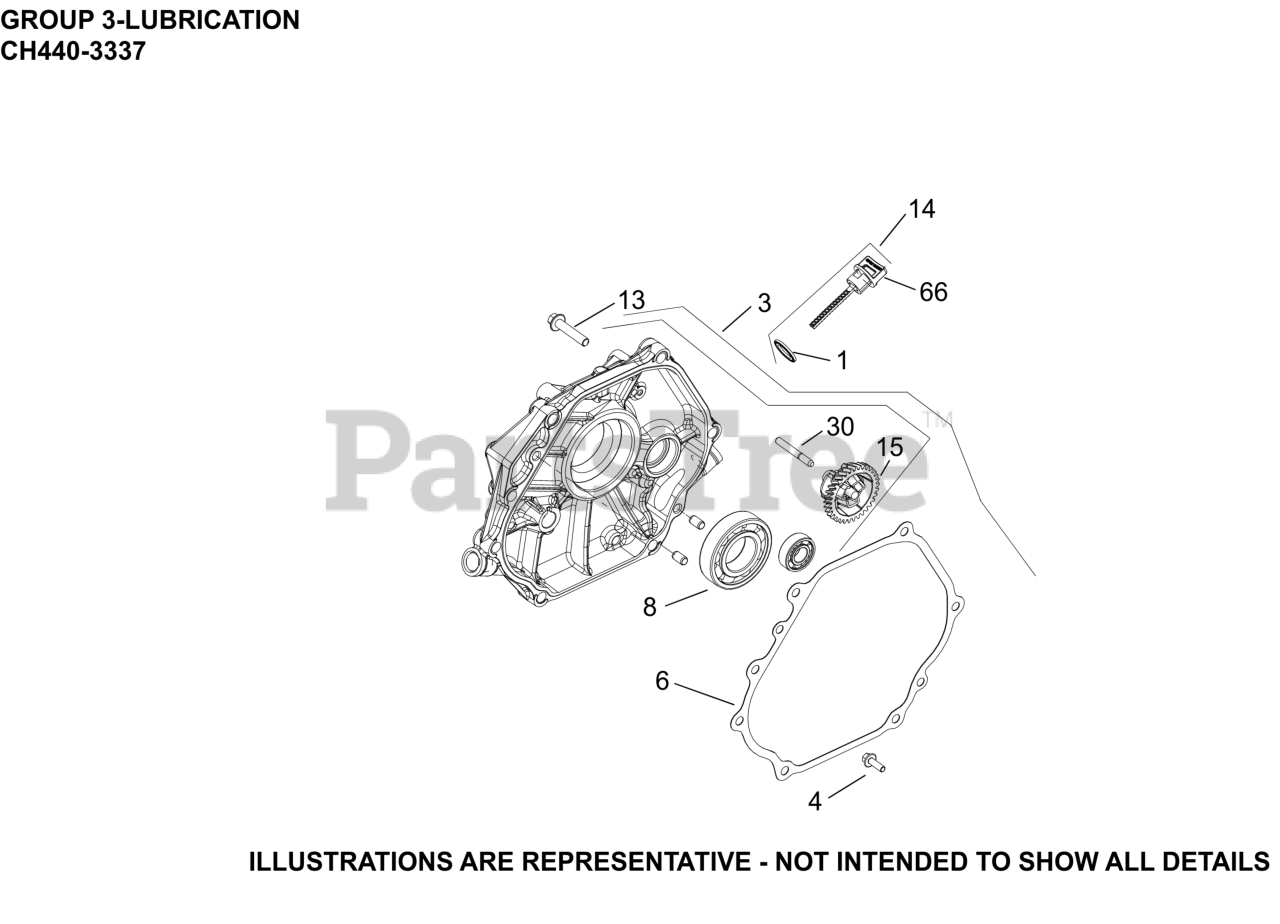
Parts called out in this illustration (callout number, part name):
1	SEAL, DIPSTICK
3	KIT, CLOSURE PLATE ASSEMBLY
4	SCREW, M6 X18
6	GASKET, CLOSURE PLATE
8	BEARING, BALL
13	SCREW, CLOSURE PLATE
14	DIPSTICK ASSEMBLY
15	GOVERNOR ASSEMBLY
30	SHAFT, GOVERNOR GEAR
66	DIPSTICK - USE 17 038 08-S
